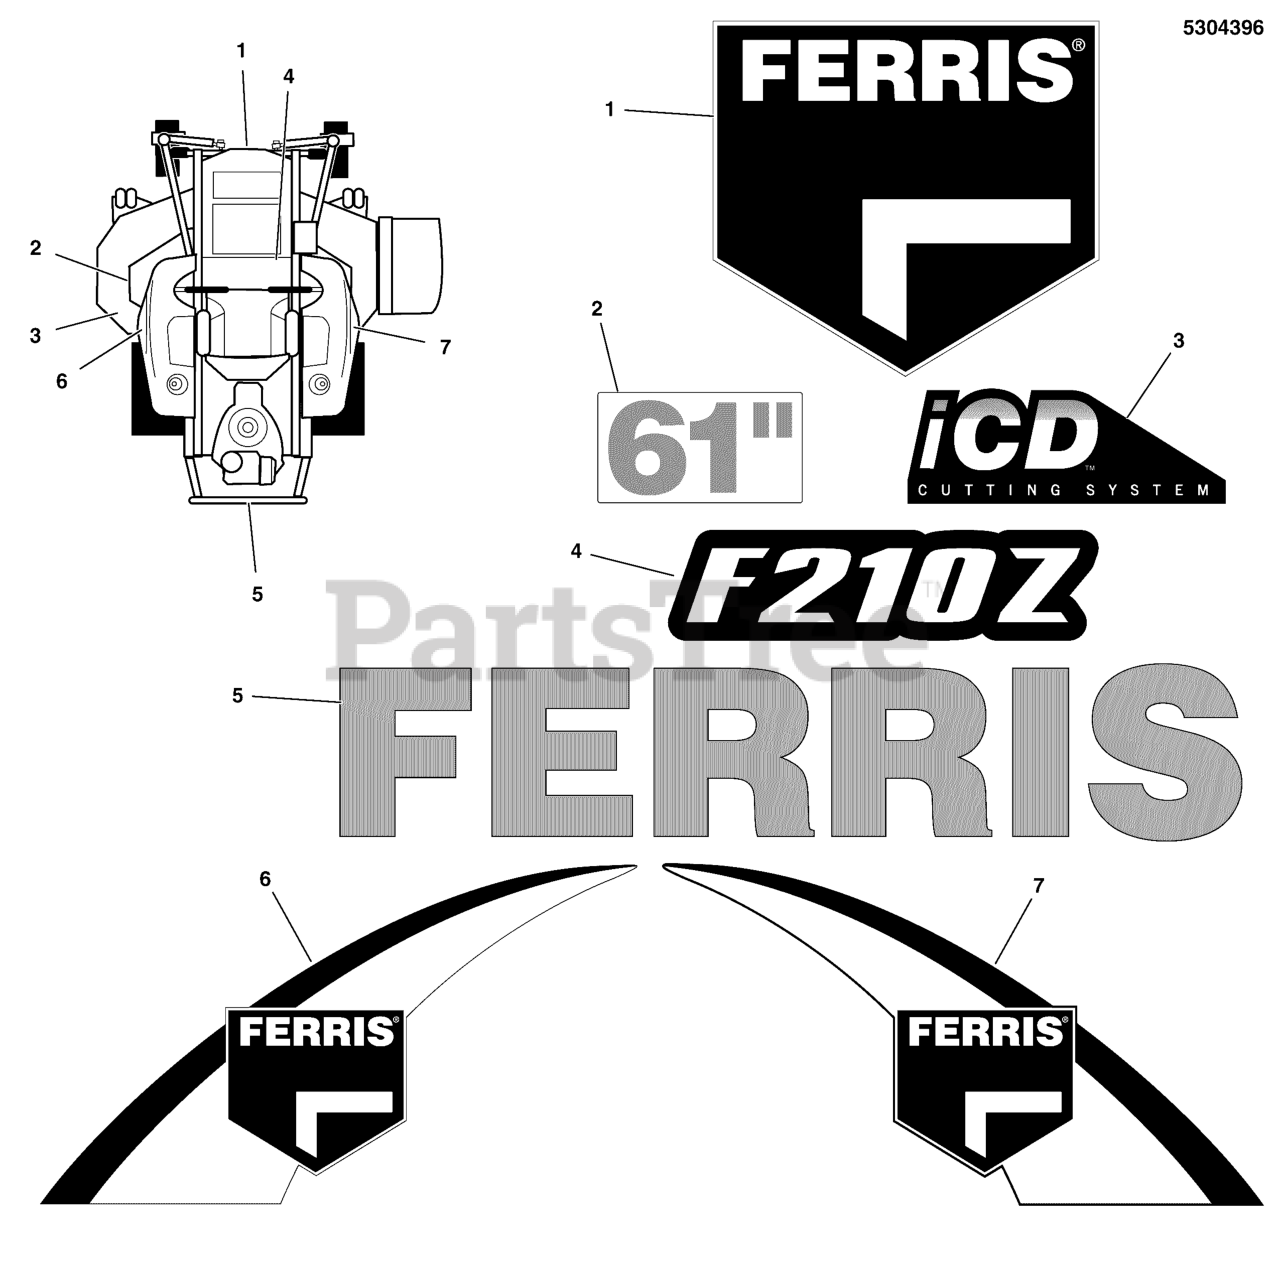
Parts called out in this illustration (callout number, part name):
1	DECAL, BRAND
2	DECAL, 61
3	DECAL, iCD CUTTING SYSTEM
4	DECAL, MODEL, F210Z
5	DECAL, FERRIS, 2.23" X 11.39"
6	DECAL, Model, Left Hand
7	DECAL, Model, Right Hand
